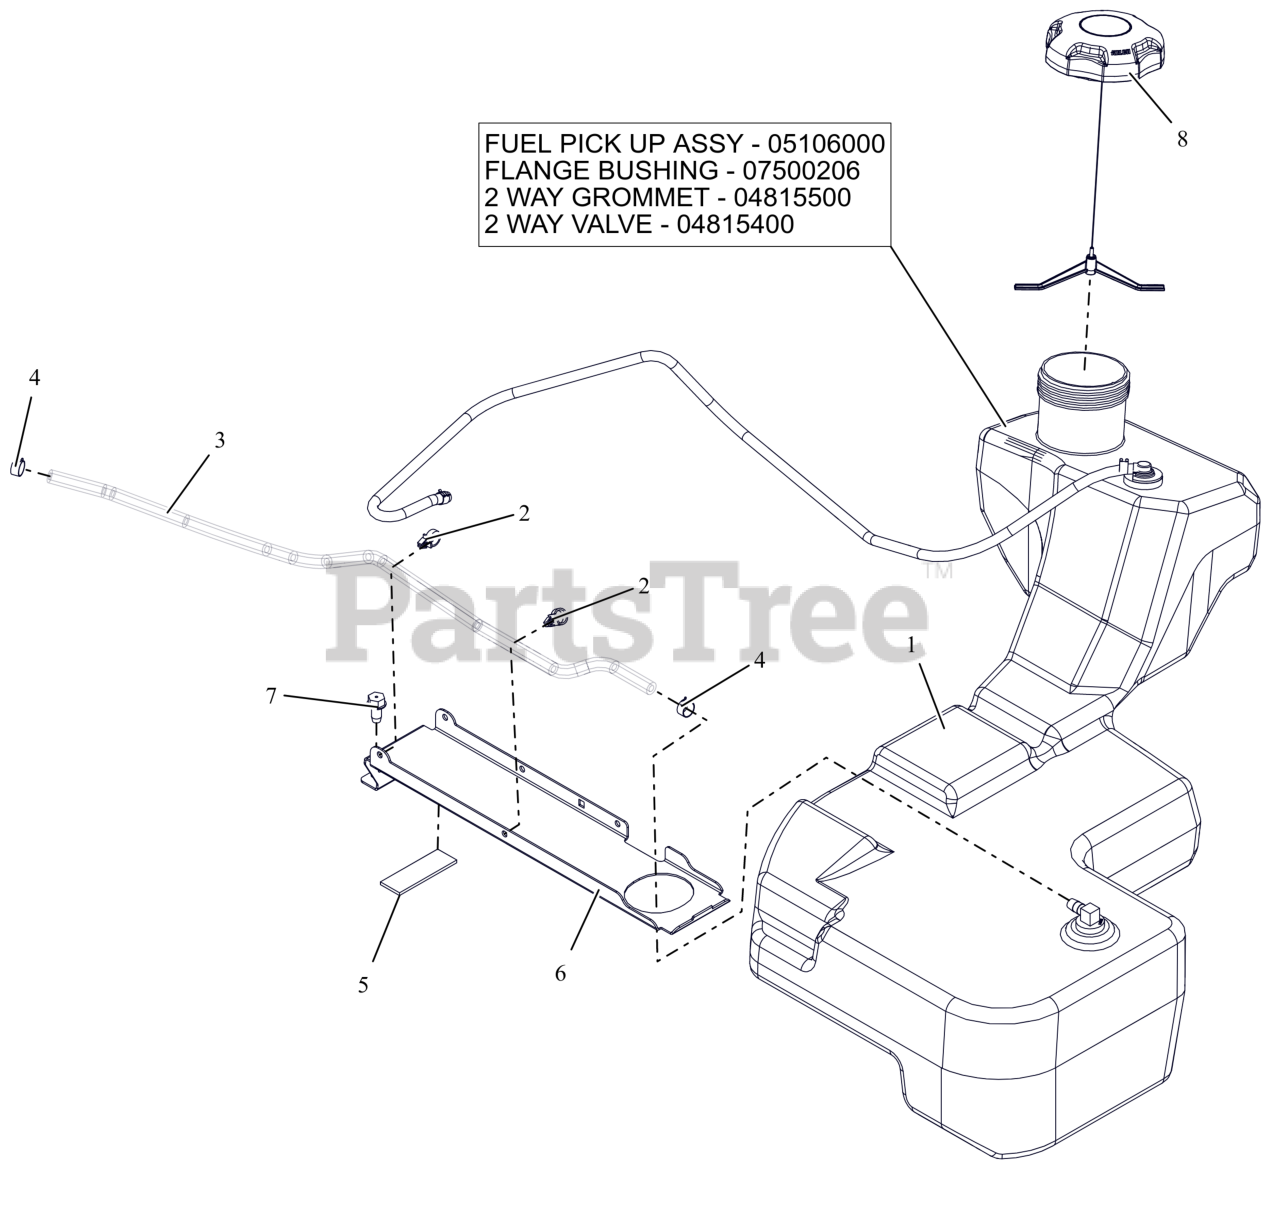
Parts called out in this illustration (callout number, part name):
1	ASM, FUEL TANK-HD
1	ASM, HD FUEL PICK-UP
1	BSHG-FLG .375X1.062X.625 NITR
1	GROMMET, 2-WAY
1	VALVE, 2-WAY
2	ROUTING CLIP (1/2" ID)
3	HOSE, .25 LOW-PERM BULK GAS
4	CLAMP, FUEL LINE
5	PAD,RBR 1.0"X3.0" W/ADHESIVE
6	BRKT, FUEL TANK HOLD DOWN
7	SCR,TAP .375-16X.75 HWH TR ZCC
8	CAP, FUEL - 3.50 RATCHET INLET VENT
